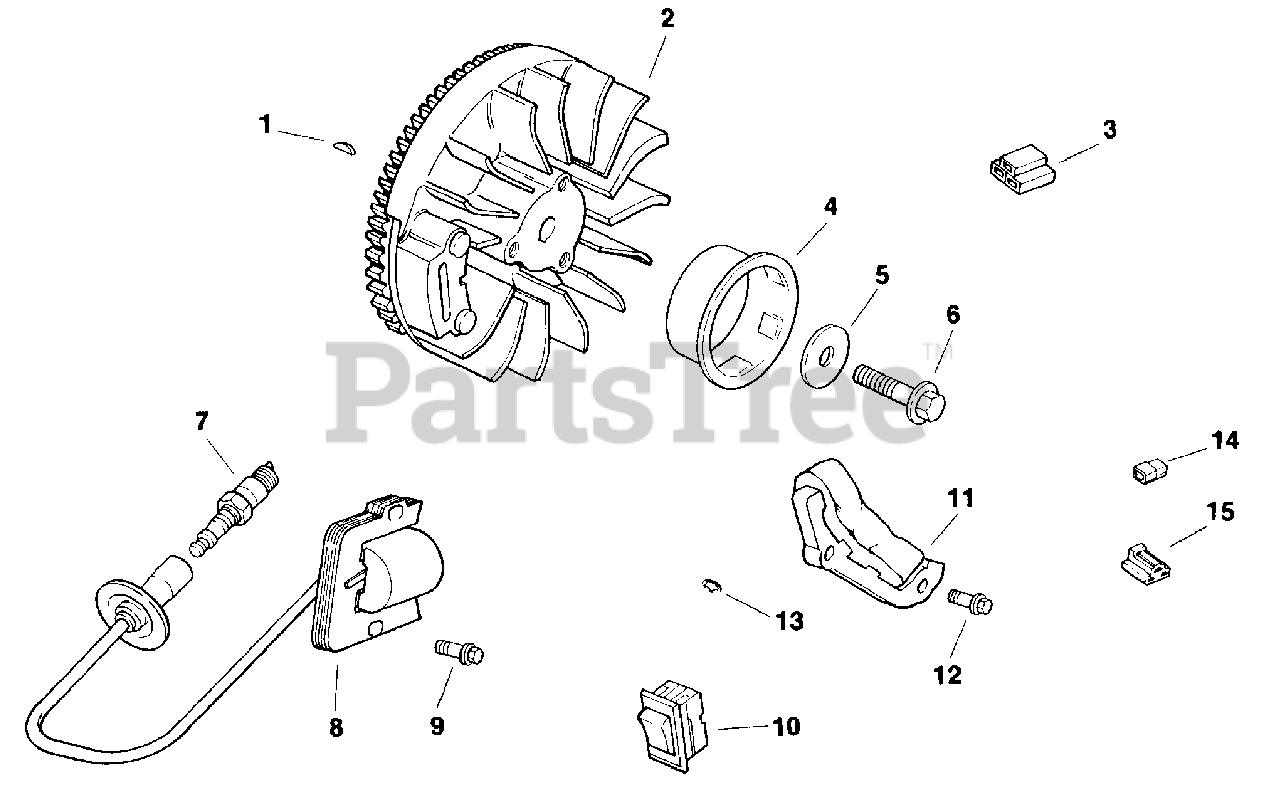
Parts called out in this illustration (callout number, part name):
1	KEY, 1/8" X 1/2"
5	WASHER, FLAT 13/32"
7	PLUG, SPARK (STD)
8	MODULE, IGNITION - DISCONTINUED
9	Screw, ignition module M5x0.8x20
10	SWITCH - DISCONTINUED
13	WASHER, INT TOOTH LOCK #10
